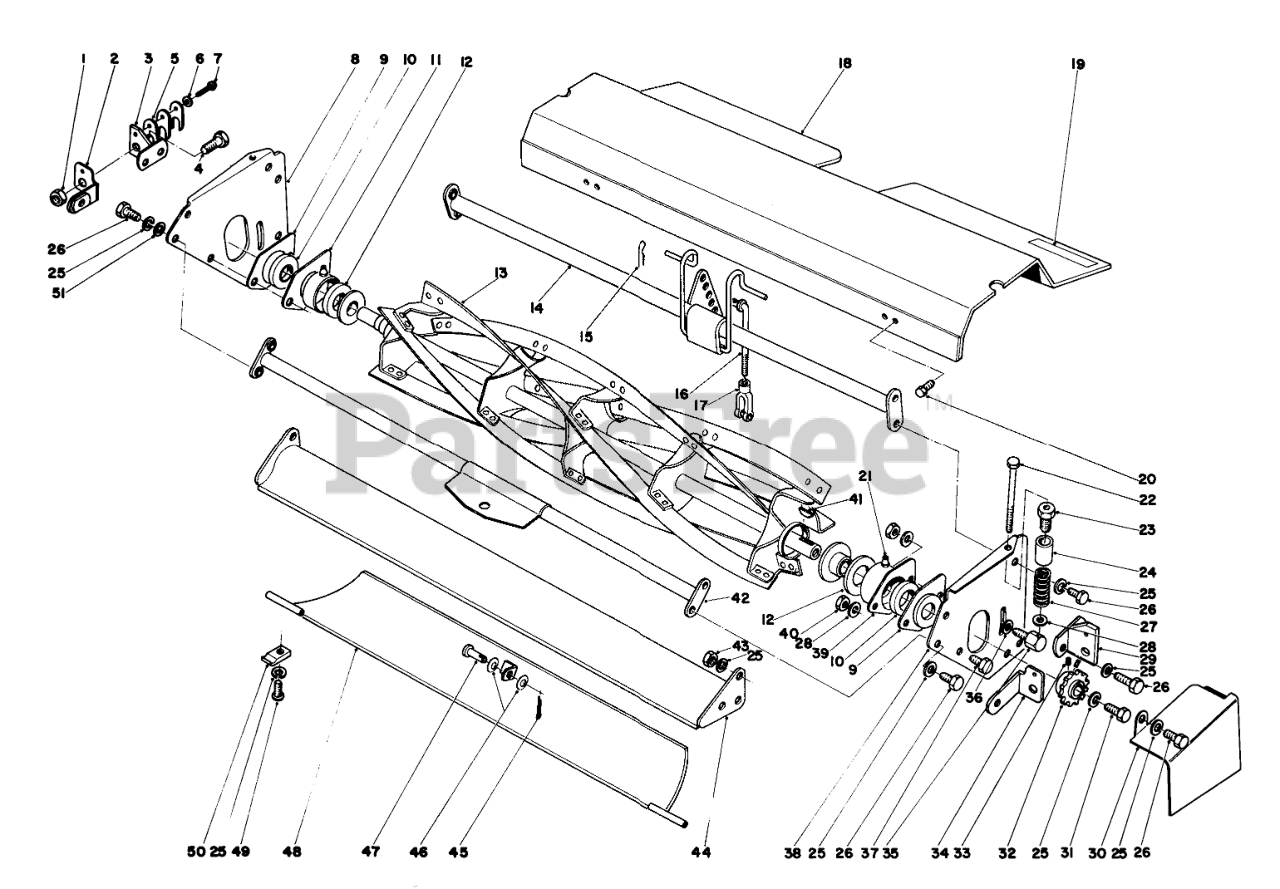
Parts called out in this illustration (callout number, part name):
1	NUT-HEX
2	Ball Joint Bracket-Right
3	Hanger-Right Hand
4	SCREW-HH
5	FRONT SIDE SHIM
6	WASHER-LOCK/SP
7	10-24 X 7/8 RND HD MS
8	Side Plate
9	Cup-Bearing
10	.6693 RP BALL BEARING
11	Cup Bearing
12	1 X .250 OIL SEAL
13	Reel Assy.
14	Tube-Reel
15	PIN-COTTER
16	Rod Adjusting
17	YOKE
18	Shield-Grass
19	WARNING DECAL
20	10-16 X 3/8 THDG SCREW
21	FITTING-GREASE
22	Screw-Adjusting
23	Bolt-Adjusting
24	ADJUSTMENT BLOCK
25	WASHER-LOCK, INTERNAL
26	SCREW-HH
27	SPRING-COMPRESSION
28	WASHER-PLAIN
29	Hanger-Left Hand
30	Chain Guard
31	SCREW-HH
32	Sprocket-Reel
33	SCREW-HSH
34	Bracket, Ball Joint
35	REEL BEARING SCREW
36	WASHER
37	BEARING CUP BOLT
38	Side Plate
39	Cup Bearing
40	NUT-LOCK
41	KEY-WOODRUFF
42	Tube-Reel
43	SCREW-HH
44	Bedknife
45	PIN-COTTER
46	WASHER-SPRING
47	PIN-CLEVIS
50	CLIP-SKID
51	WASHER-FLAT
